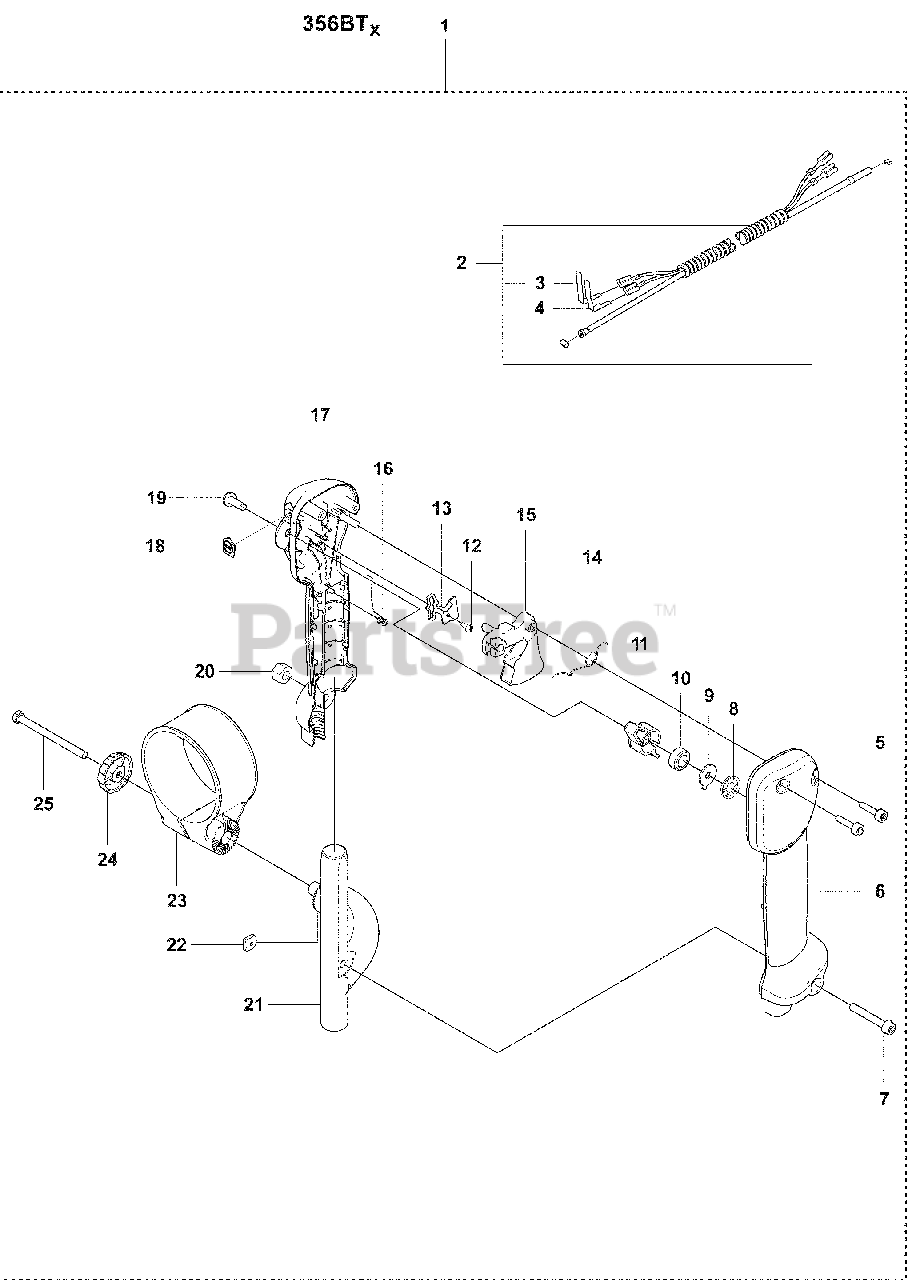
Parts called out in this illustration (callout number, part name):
1	Handle Assembly
2	WIRING ASSY
3	Contact Spring
4	Contact Spring
5	Screw
6	Right Half Handle
10	Spring, Rubber
11	Stop Lever
17	Left Half Handle
19	Pivot Shaft
22	Square Nut
24	Air Filter Cover Knob
